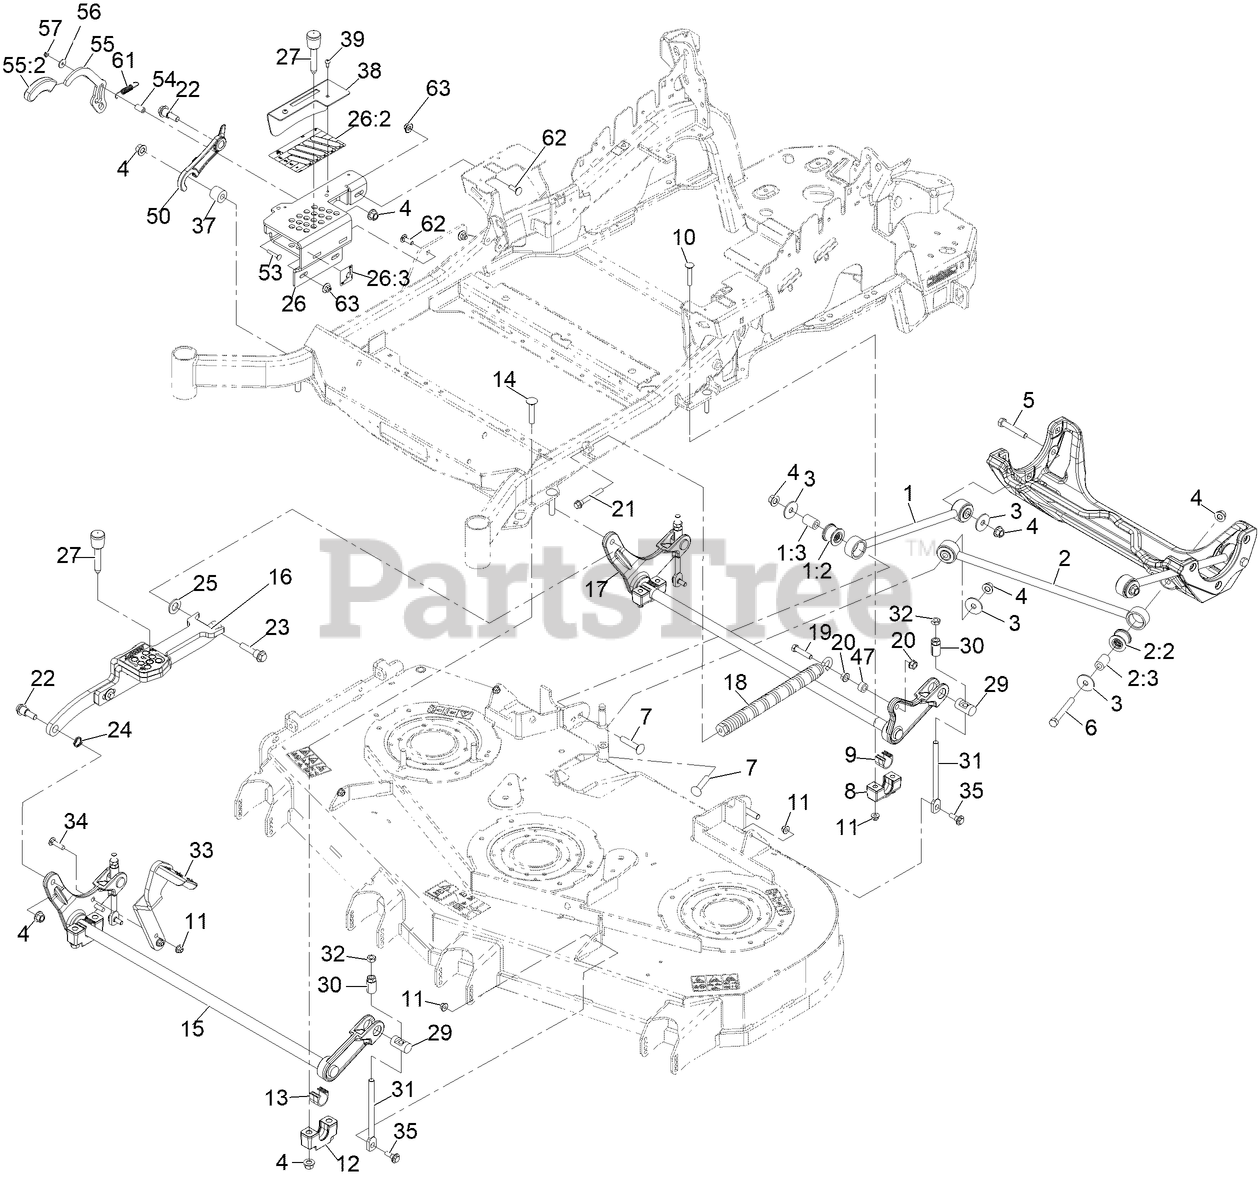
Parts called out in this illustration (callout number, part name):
1	DECK STRUT ASM
1:2	BUSHING-SUSPENSION, RUBBER
2	PANHARD ROD ASM
2:2	BUSHING-SUSPENSION, RUBBER
3	WASHER-THRUST
4	Nut-Lock 1/2-13
5	SCREW-HH
6	SCREW-HH
7	SCREW-CARR
8	SUPPORT-CROSS SHAFT, BEARING REAR
9	BEARING-CROSS SHAFT, REAR
10	Bolt-Carriage 3/8-16 X 2 1/4
11	NUT-HF, NI
12	SUPPORT-CROSS SHAFT, BEARING
13	BEARING-CROSS SHAFT, FRON
14	Bolt-Carriage 1/2-13 X 2 1/2 Spl Neck
15	Shaft- Deck Lift Front [black]
16	LINK-LIFT, DECK
17	Shaft- Deck Lift Rear [black]
18	SPRING-EXTENSION
19	SCREW-HH
21	BOLT-SHOULDER
22	SCREW-SHOULDER, HHF 1/2-13 X 1.12
23	SCREW-HHF, SHOULDER
24	WASHER-WAVE
25	WASHER-FLAT
26	ASM-HOC Box W/ Decals
26:2	Decal-HOC
26:3	DECAL-PARK BRAKE, CE
27	ASM- HOC PIN
29	TRUNNION
30	ADJUSTER-LIFT, DECK
31	LINK-ADJUSTER, DECK LIFT
32	NUT-JAM
33	LEVER-FOOT
34	SCREW-CARR
35	SCREW-SHOULDER, HHF
37	Bushing- Link
38	COVER-TRANSPORT LOCK
39	SCREW-TPH THD FORM
50	Latch-Transport, HOC
53	SCREW-CARR
54	Spacer- 0.50" OD
55	ASM-TRANSPORT LOCK LEVER W/ GRIP
55:2	GRIP-HANDLE, STEERING
57	NUT-LOCK, NI
61	Spring- Extension
62	Bolt-Carriage 3/8-16 X 1 1/4
63	Nut-Nyloc 3/8-16 Flg
